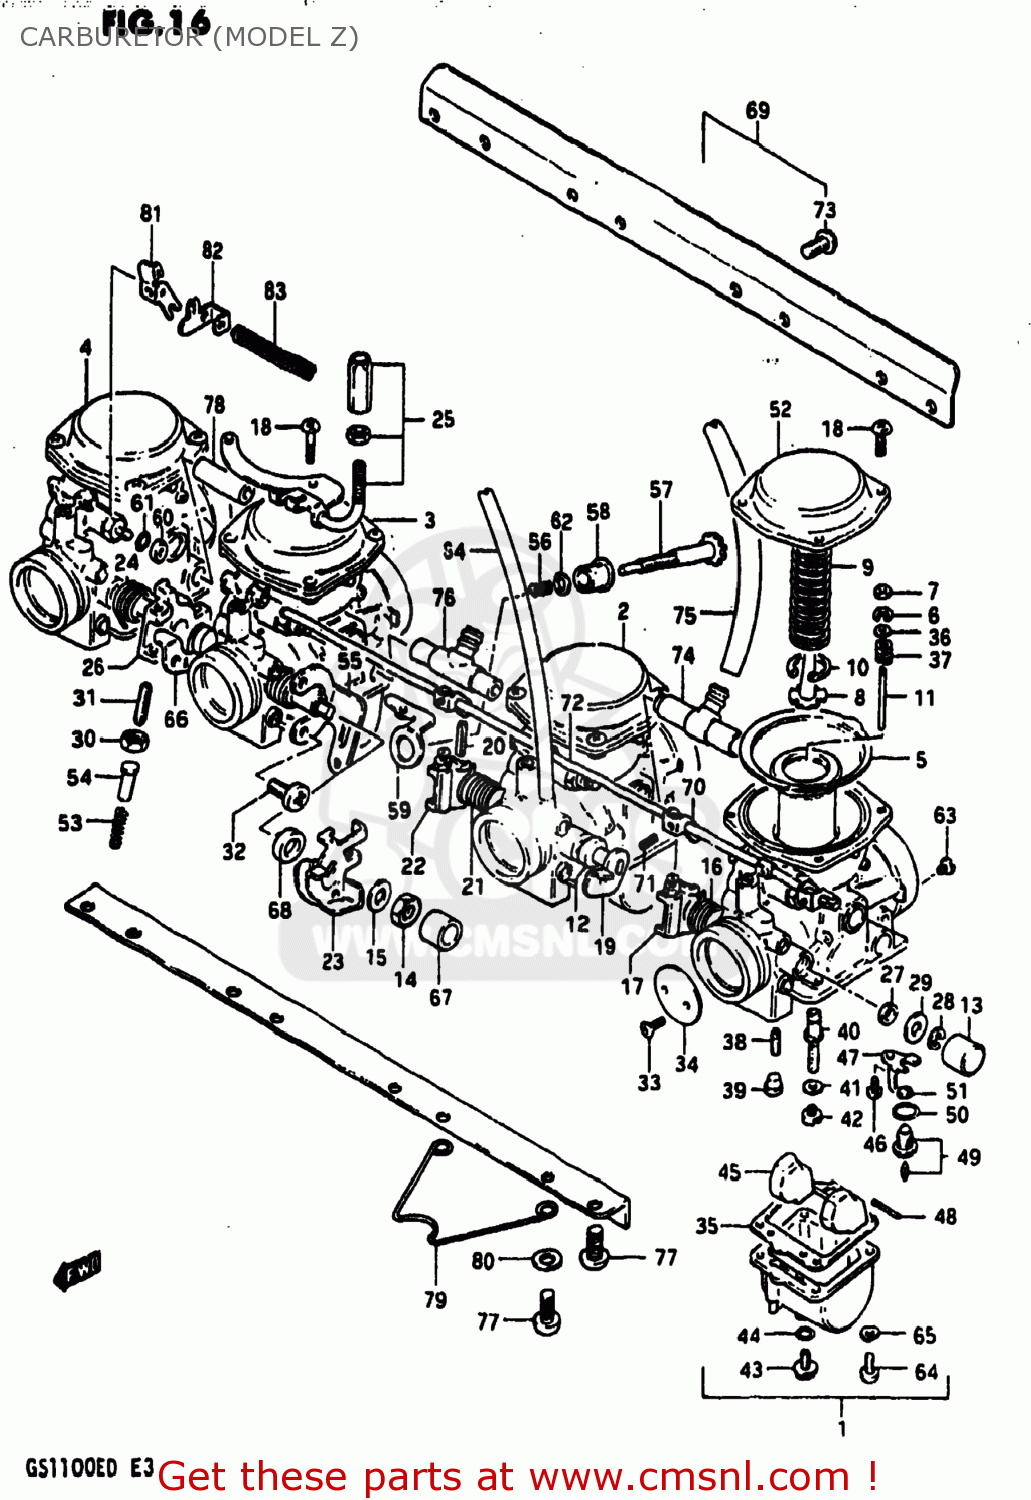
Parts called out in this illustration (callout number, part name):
1	CARBURETOR ASSEMBLY
2	CARBURETOR ASSEMBLY
3	CARBURETOR ASSEMBLY
4	CARBURETOR ASSEMBLY
5	DIAPHRAGM ASSEMBLY
6	CLIP,NEEDLE
7	RING
8	HOLDER,GUIDE
9	SPRING
10	E RING
11	NEEDLE,JET
12	GASKET
13	CAP
14	NUT
15	WASHER
16	SPRING,THROTTLE SHAFT
17	SHAFT,THROTTLE
18	SCREW
19	SHAFT,THROTTLE
20	PIN,THROTTLE SHAFT
21	SPRING,THROTTLE SHAFT
22	LEVER,THROTTLE SHAFT
23	LEVER ASSEMBLY,THROTTLE
24	SPRING,THROTTLE SHAFT
25	BRACKET,THROTTLE CABLE
26	SHAFT,THROTTLE
27	SEAL
28	E RING
29	GASKET,THROTTLE SHAFT (NAS)
30	NUT
31	SCREW
32	SCREW
33	SCREW
34	VALVE,THROTTLE (BUTTERFLY)
35	GASKET,FLOAT CHAMBER (NAS)
36	WASHER
37	SPRING
38	JET,PILOT
39	PLUG,NEEDLE JET
40	JET,NEEDLE
41	WASHER,NEEDLE NOZZLE
42	JET,MAIN(110)
43	PLUG,DRAIN
44	GASKET (NAS)
45	FLOAT
46	SCREW 4X6
47	PLATE,NEEDLE VALVE FITING
48	PIN,FLOAT
49	VALVE ASSEMBLY,NEEDLE
50	O-RING,NEEDLE VALVE
51	FILTER
52	COVER,DIAPHRAGM
53	SPRING,THROTTLE SCREW
54	PIN,THROTTLE LEVER
55	BRACKET,THROTTLE ADJUST
56	SPRING
57	SCREW
58	BUSH
59	BRACKET,THROTTLE ADJUST
60	CAP,STARTER VALVE
61	O RING
62	WASHER
63	JET,AIR
64	SCREW
65	LOCK WASHER
66	SHAFT,THROTTLE
67	RING
68	RING
69	CARBURETOR ASSEMBLY
70	LEVER
71	SCREW
72	SHAFT,STARTER
73	SCREW
74	NIPPLE
75	HOSE,CARBURETOR
76	NIPPLE
77	SCREW
78	NIPPLE
79	CLIP
80	WASHER
81	LEVER,CHOKE CABLE
82	PLATE,CHOKE CABLE
83	SPRING,CHOKE CABLE
84	HOSE
